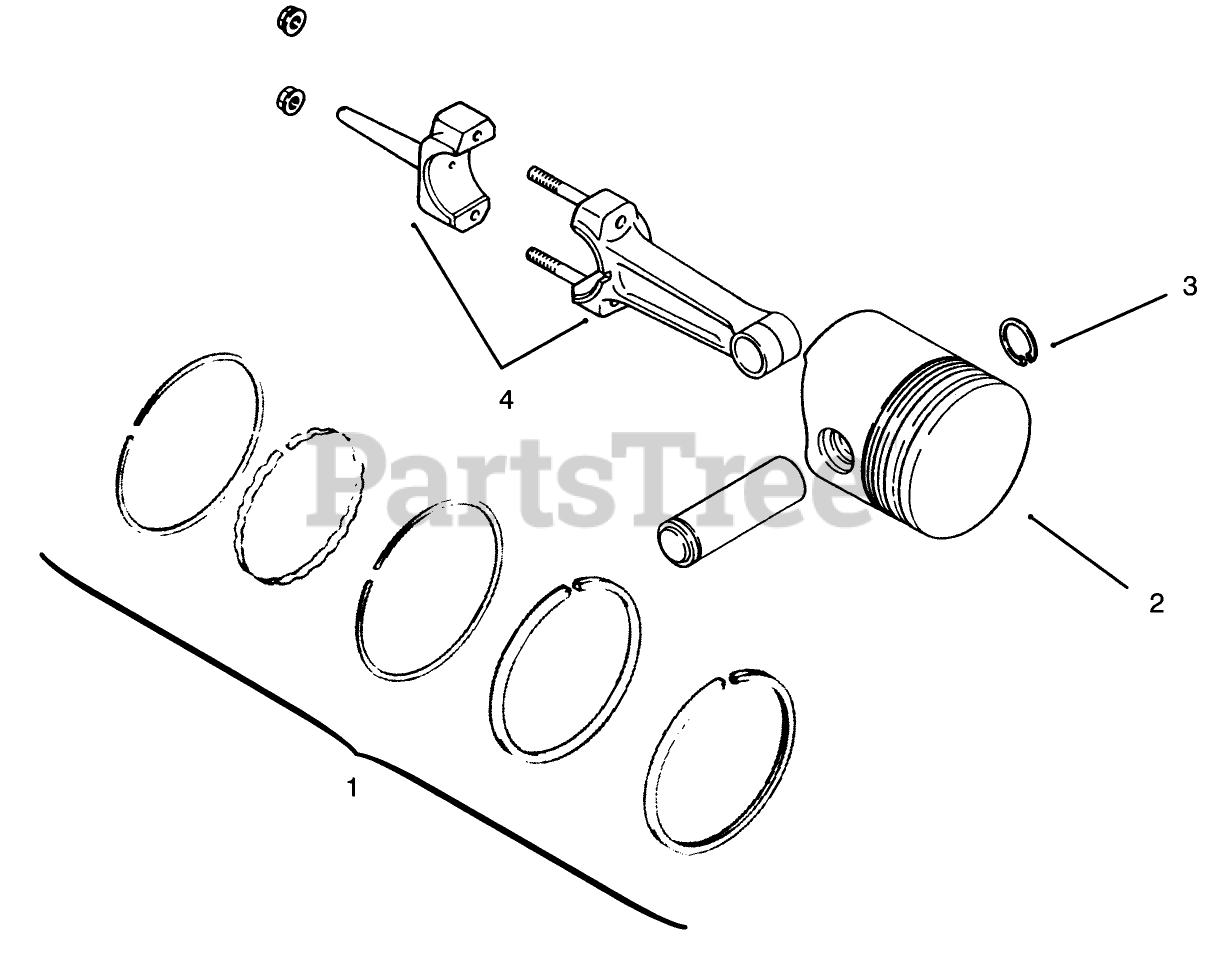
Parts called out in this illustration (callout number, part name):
1	VNDR #47-108-05
2	VNDR #47-874-21
3	KOHLER 47-018-01
4	VNDR #45-067-24
